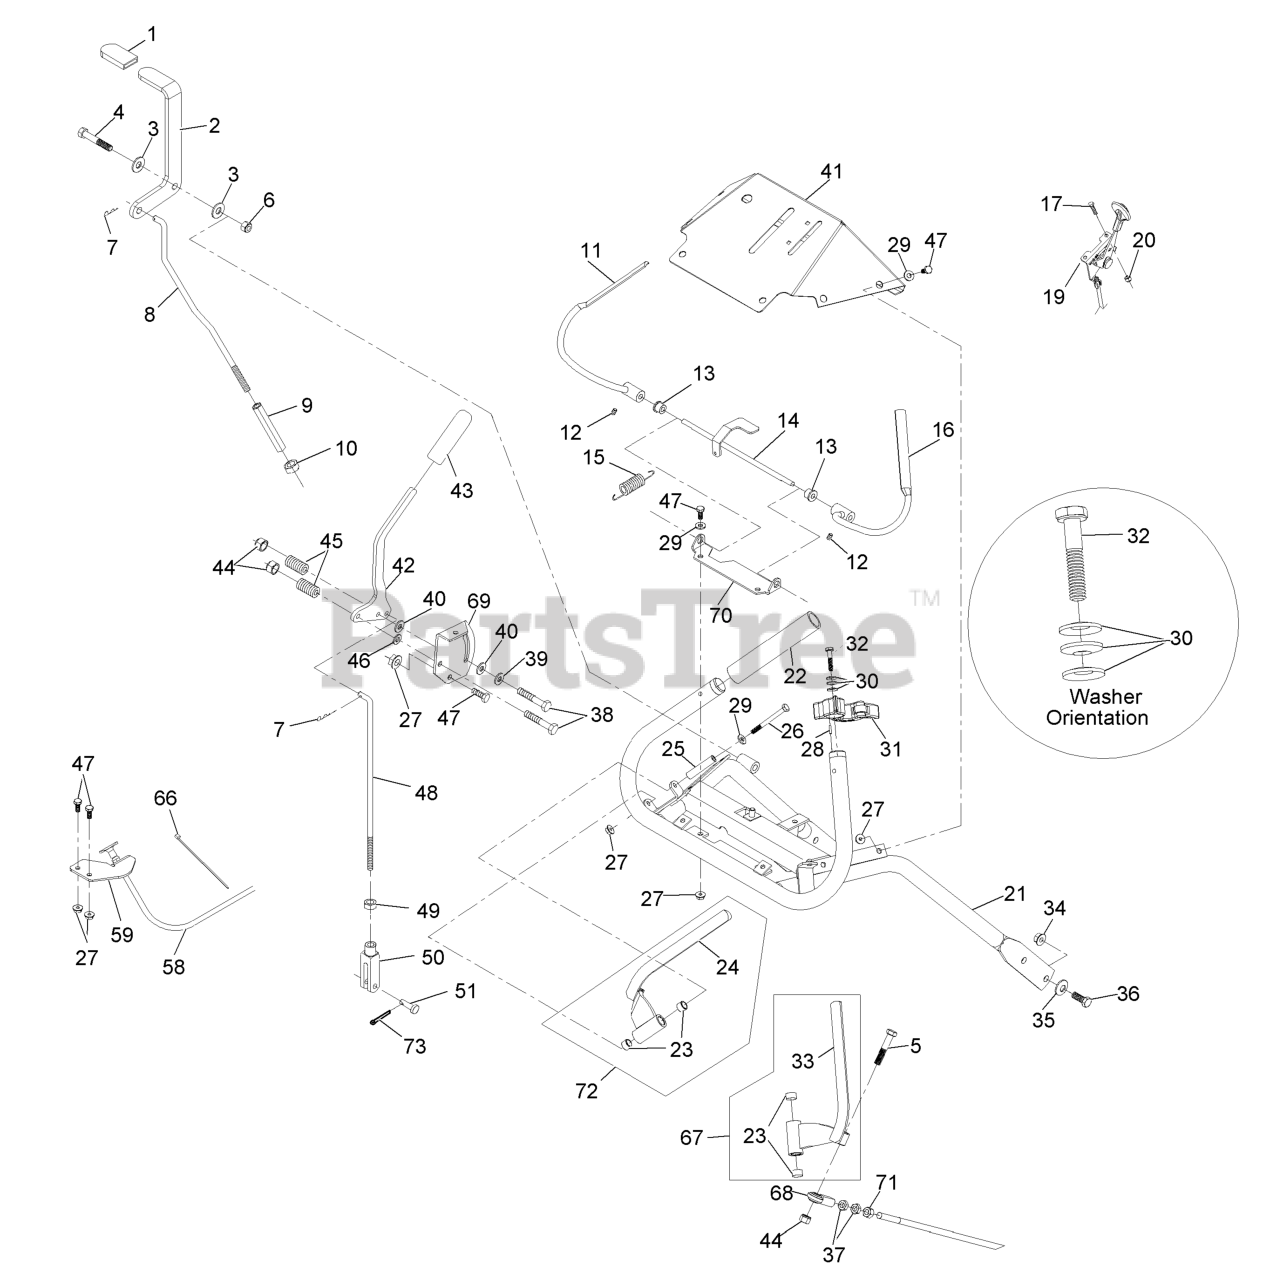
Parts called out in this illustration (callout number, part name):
1	GRIP-LEVER
2	ASM, LEVER W/GRIP
3	WASHER-FLAT
4	SCREW-HH
5	SCREW-HH
6	NUT-LOCK, NI
7	PIN-COTTER
8	LINK,BLADE ENGAGE (PLTD)
9	TURNBUCKLE
10	NUT-HEX
11	WLD,LH OPC LEVER
12	SCREW-SET
13	BUSHING-NYLON
14	WLD,OPC LEVER AXLE
15	SPRING-EXTENSION
16	WLD,RH OPC LEVER
17	BOLT-CARR
19	CONTROL, THROTTLE
20	NUT-LOCK, NI
21	WLD,UPPER ECS HANDLE
22	GRIP-BAR, HANDLE
23	BUSHING-SLEEVE
24	Lever, Drive Lh
25	BUSHING-LEVER, DRIVE
26	SCREW-HH
29	WASHER-FLAT
30	WASHER-SPRING
31	ASM,LATCH RH THUMB
31	ASM,LATCH LH THUMB
32	SCREW-HH
33	Lever, Drive Rh
34	NUT-HHF, WHIZ
35	WASHER-BELLEVILLE
36	SCREW-HH
37	NUT-HJ
38	SCREW-HH
39	WASHER-FRICTION
40	WASHER-FRICTION
41	ASM,CONSOLE W/DECALS
42	LEVER, SHIFT W/GRIP
43	GRIP-HANDLE, STEERING
44	NUT-LOCK, NI
45	SPRING-COMPRESSION
46	WASHER-PLAIN
47	SCREW-HH
48	ROD,SPEED CONTROL
49	NUT-JAM
50	YOKE-ADJUSTABLE
51	PIN-CLEVIS
58	CABLE-CHOKE
59	BRACKET-CABLE, CHOKE
66	TIE-CABLE
67	DRIVE LEVER-ASM, RH
68	JOINT-BALL, END
69	BRACKET,SHIFTER SLIDE (PL
70	BRACKET,OPC AXLE
71	NUT-HEX
72	DRIVE LEVER-ASM, LH
73	PIN-COTTER
